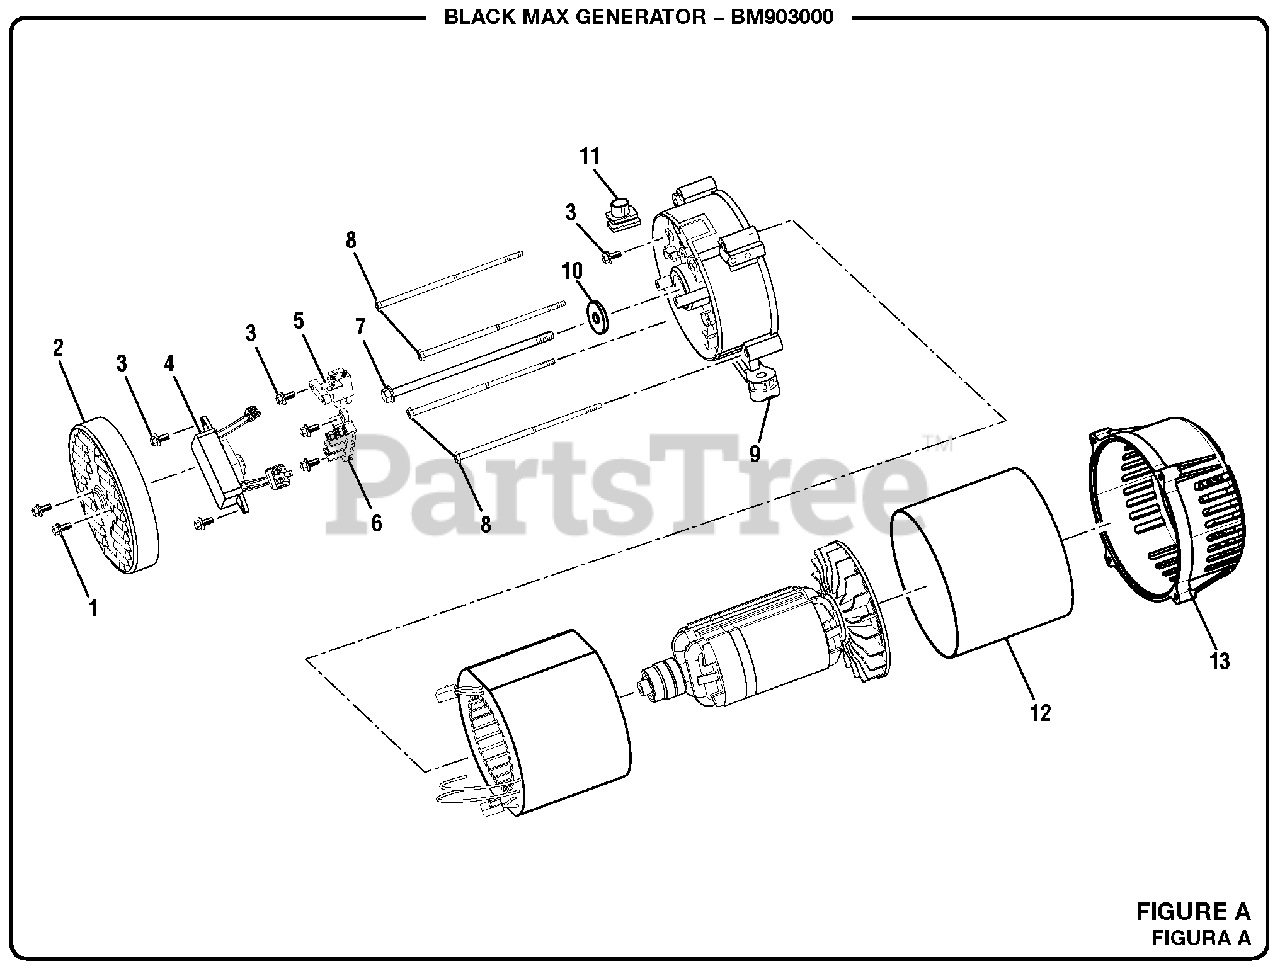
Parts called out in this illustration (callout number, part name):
1	Bolt (M5 x 10 mm, Hex Hd)
2	Brush Cover
3	Bolt (M5 x 16 mm, Hex Hd)
4	Automatic Voltage Regulator
5	Brush Assembly
6	Terminal Block
7	Bolt (5/16-24 x 182 mm, Hex Hd)
8	Bolt (M6 x 180 mm, Hex Hd)
9	Bearing Housing
10	Washer (ID84 x OD251 x 3t)
11	Rubber Boot
12	Generator Head Cover
13	Adaptor Housing
